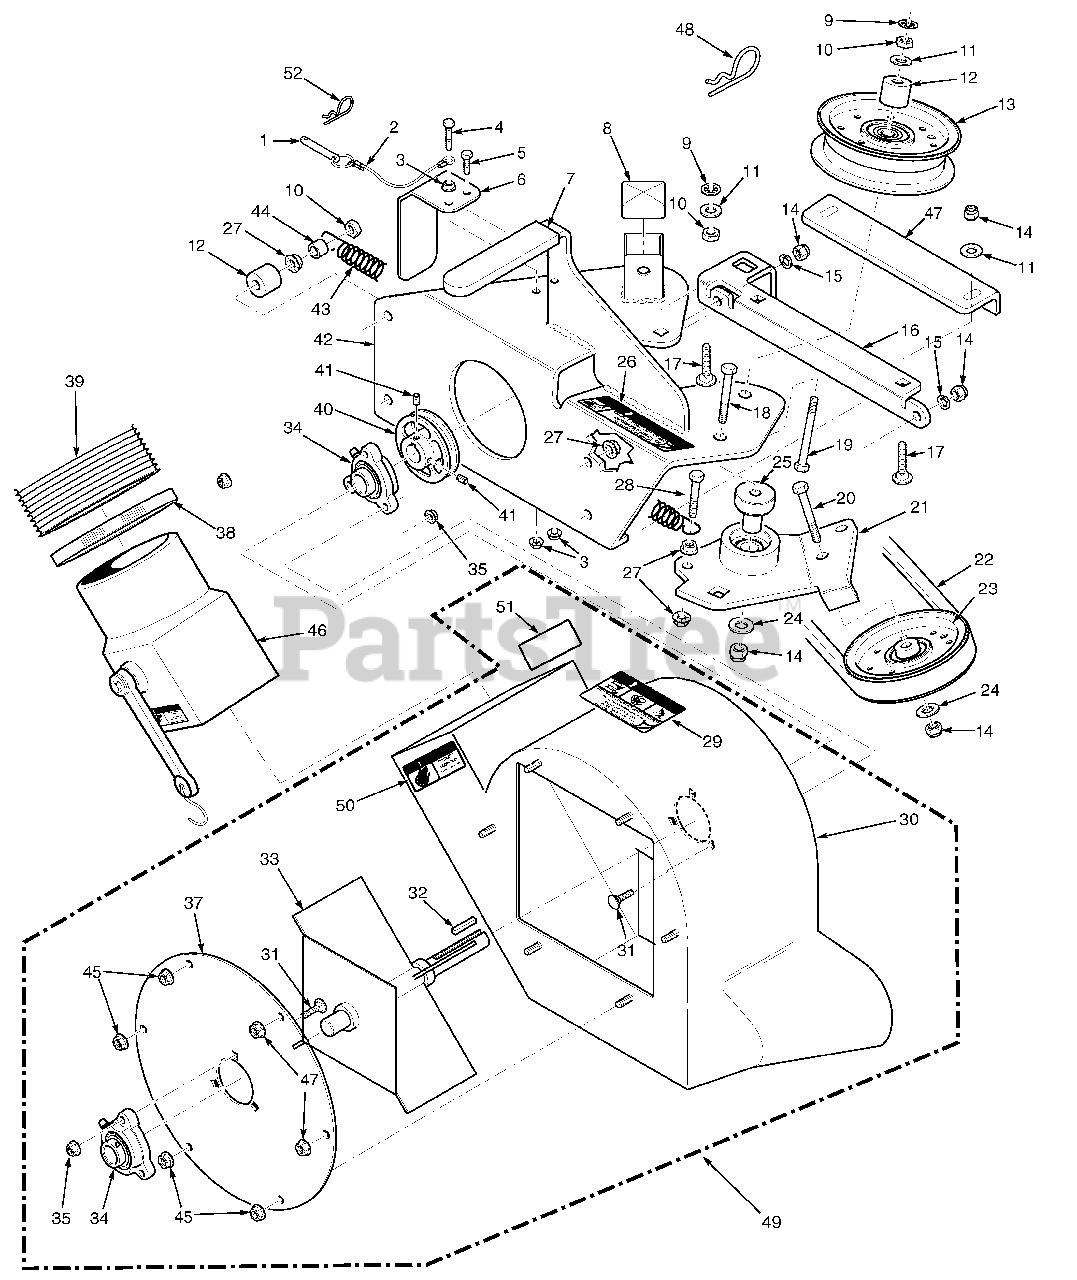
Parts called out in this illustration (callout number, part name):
1	Pin, Ring 2-1/4" Long
2	Lanyard, Deck Height Pin
3	Nut, Serr. Flange 1/4-20
4	Bolt, Hex Head 1/4-20 x 1-1/4"
5	Bolt, Hex Head 1/4-20 x 3/4"
6	Belt Cover, Rear
7	Grip, Blower Lever
8	Cap, Square
9	Nut, Push On 3/8 Thread
10	Lock Nut, 3/8-16
11	Flatwasher, 3/8-.391 x .938 x .105
12	Spacer
13	Pulley, Idler 3" Dia. - 52"
13	Pulley, Idler 4" Dia. - 61" & 72"
14	Nut, Elastic Stop 3/8-16
15	Lockwasher, 3/8-16
16	Plate, Catch Mounting
16	Plate, Catch Mounting - 72"
17	Bolt, Carr. 3/8-16 x 1-1/2"
18	Bolt, Hex Head 3/8-16 x 3" - 52"
18	Bolt, Hex Head 3/8-16 x 2-1/4"
19	Bolt, Hex Head 3/8-16 x 3-1/2"
20	Bolt, Hex Head 3/8-16 x 1-3/4"
21	Idler Arm Assembly, GC-STT 52"
21	Idler Arm Assembly, GC-STT 61"
22	Belt, GC-STT 52"
22	Belt, GC-STT 61"
23	Pulley, 3-1/2" O.D., GC-STT
24	Washer, 3/8 Hardened
25	Pivot, Idler - 52"
25	Pivot, Idler - 61"
26	Decal, Belt Cover
27	Nut, Serr. Flange 3/8-16
28	Bolt, Hex Head 3/8-16 x 1-1/2 Gr. 8
29	Decal, Danger
30	Blower Housing w/Decals
31	Bolt, Carr. 5/16-18 x 3/4" Gr. 5
32	Key, 1/4 x 1/4 x 1-1/2"
33	Fan Weldment
34	Bearing Assembly
35	Nut, Elastic Stop 5/16-18
36	Flatwasher, 5/16-.344 x .688 x .065
37	Cover, Blower Housing
38	Clamp, 8-5/8" Max Dia.
39	Hose, 8.00" Dia. x 60.50" Long
39	Hose, 8.00" Dia. x 68.00" Long
40	Pulley, 4-3/4" O.D. - 1" Bore
41	Set Screw, 5/16-18 x 3/8"
42	Frame, Blower Mount - 52"
42	Frame, Blower Mount - 61"
43	Spring, Main Drive
44	Spacer
45	Nut, Serr. Flange 5/16-18
46	Adapter w/Strap
47	Plate, Blower Catch
48	Hair Pin Cotter, .243 x 4"
49	Blower Housing Assembly, GC-STT
50	Decal, Rotating Blower
51	Decal, Blower
52	Hair Pin Cotter, .177 x 3-1/4"
